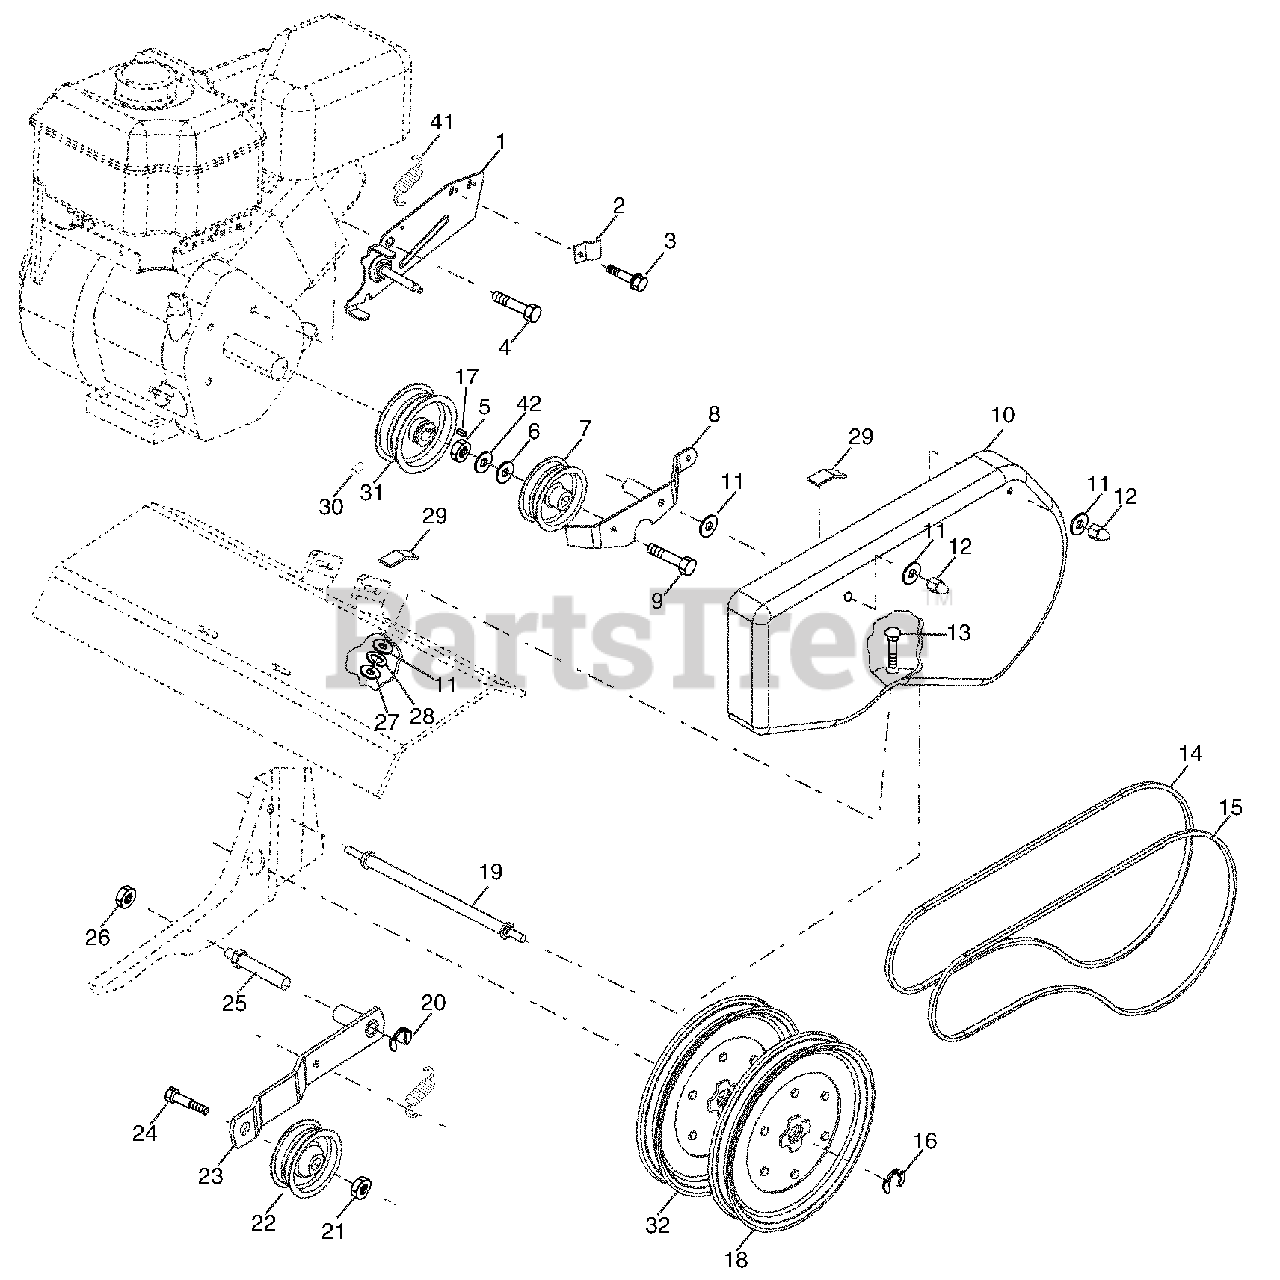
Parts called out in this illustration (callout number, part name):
1	Assembly, Bracket, Belt Guard
2	Clip, Cable
3	Screw, Hex, Washer Hd., Slotted, Thd. Cutting #10-24 x 1/2 Type D
4	Bolt, Hex 1/2-20 x 3/4
5	Nut, Hex Lock 3/8-16
6	Washer 13/32 x 13/16 x 16 Ga.
7	Pulley, Idler, Reverse
8	Assembly, Arm, Reverse Idler
9	Bolt, Hex 3/8-16 x 1-3/4
11	Washer 9/32 x 5/8 x 16 Ga.
12	Nut, Cap 1/4- 20
13	Bolt, Carriage 1/4-20 x 3/4
14	V-Belt (Forward Motion)
15	V-Belt (Reverse)
16	Ring, Retainer
17	Key, Square
18	Pulley, Flat, Trans.
19	Bolt, Belt Guard
20	Ring, Klip
21	Nut, Hex, Jam 3/8-16
22	Pulley, Idler
24	Bolt, Hex 3/8-16 x 1-1/4
25	Shaft, Idler Arm
26	Nut, Hex, Jam 5/16-18
27	Nut, Fin Hex 1/4-20
28	Washer LK Hvy Helical 1/4
29	Pad, Idler
30	Screw, Set, Socket, Headless C.P. 1/4-20 x 1 /4
31	Sheave, Engine
32	Pulley, V-Groove, Trans.
41	Spring
42	Spacer
